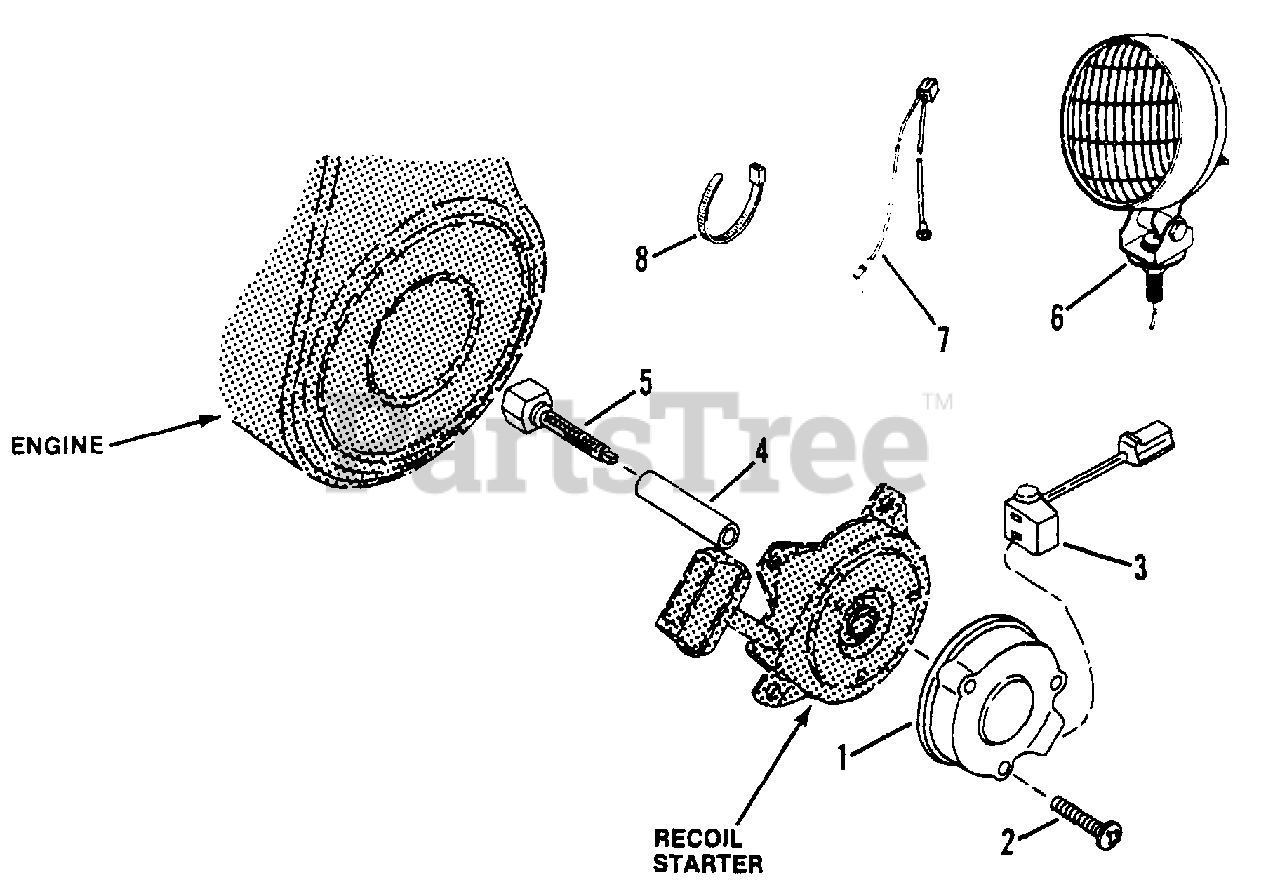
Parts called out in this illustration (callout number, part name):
1	ALTERNATOR
2	SCREW, Self-Tapping
3	CONNECTOR, AC (Yellow Leads)
4	TUBE, Centering
5	SHAFT, Alternator
6	LIGHT, Assembly
7	WIRE HARNESS
8	TIE, Wire Harness
